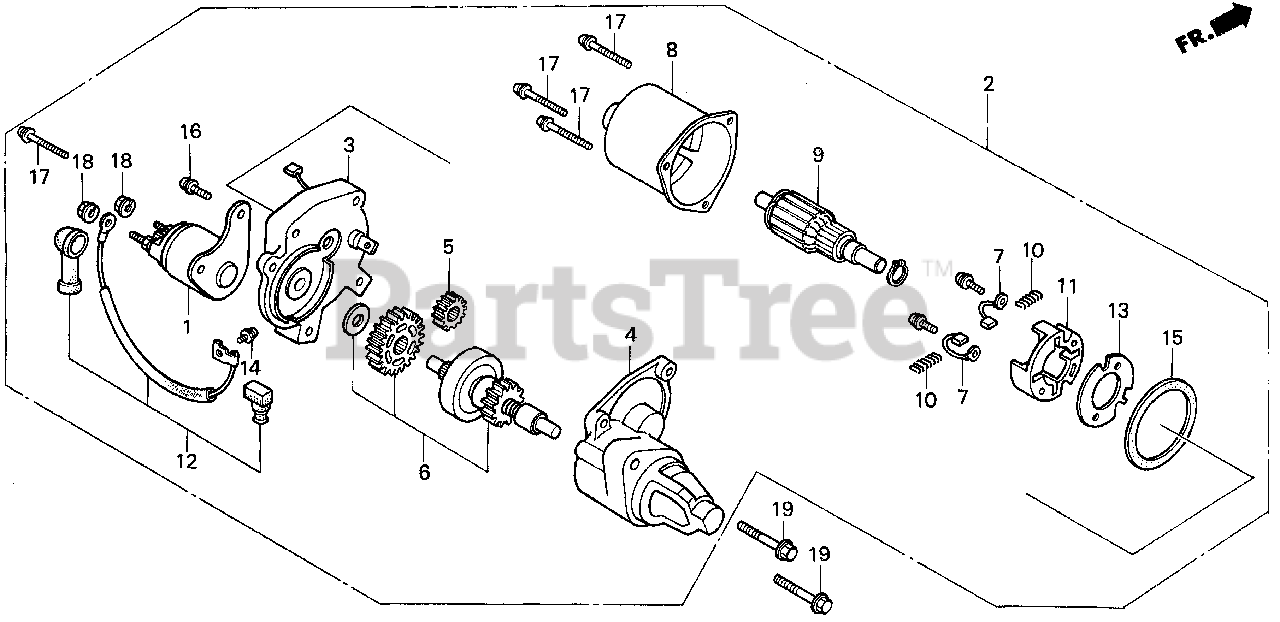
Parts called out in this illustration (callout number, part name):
1	CONTACTOR ASSY.
2	MOTOR UNIT, STARTER
3	BRACKET, CENTER
4	BRACKET, FR.
5	GEAR, DRIVE PINION
6	CLUTCH, OVERRUNNING
7	BRUSH
8	YOKE
9	ARMATURE
10	SPRING, BRUSH RETURN
11	HOLDER, BRUSH
12	WIRE, WATER COVER
13	INSULATOR
14	SCREW-WASHER (4X6)
15	GASKET
16	SCREW-WASHER (5X14)
17	SCREW-WASHER (5X3)
18	NUT-WASHER (6MM)
19	BOLT, FLANGE (8X40) Use up to Engine SN 1003236.
